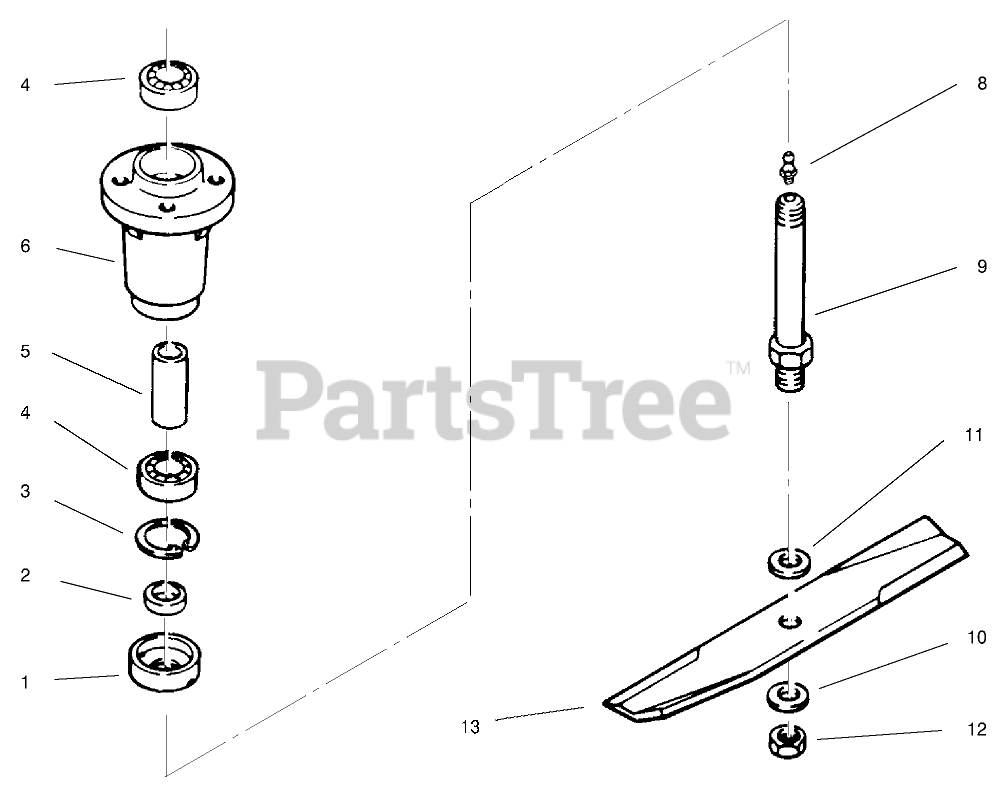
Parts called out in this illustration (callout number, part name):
1	CUP-SPINDLE
2	SPACER-BLADE
3	RING-RETAINING
4	BEARING-BALL
6	HOUSING-SPINDLE
8	FITTING-GREASE
9	SHAFT-SPINDLE
10	WASHER-FLAT
11	WASHER-FLAT
12	NUT-JAM
13	BLADE KIT (3 PACK)
